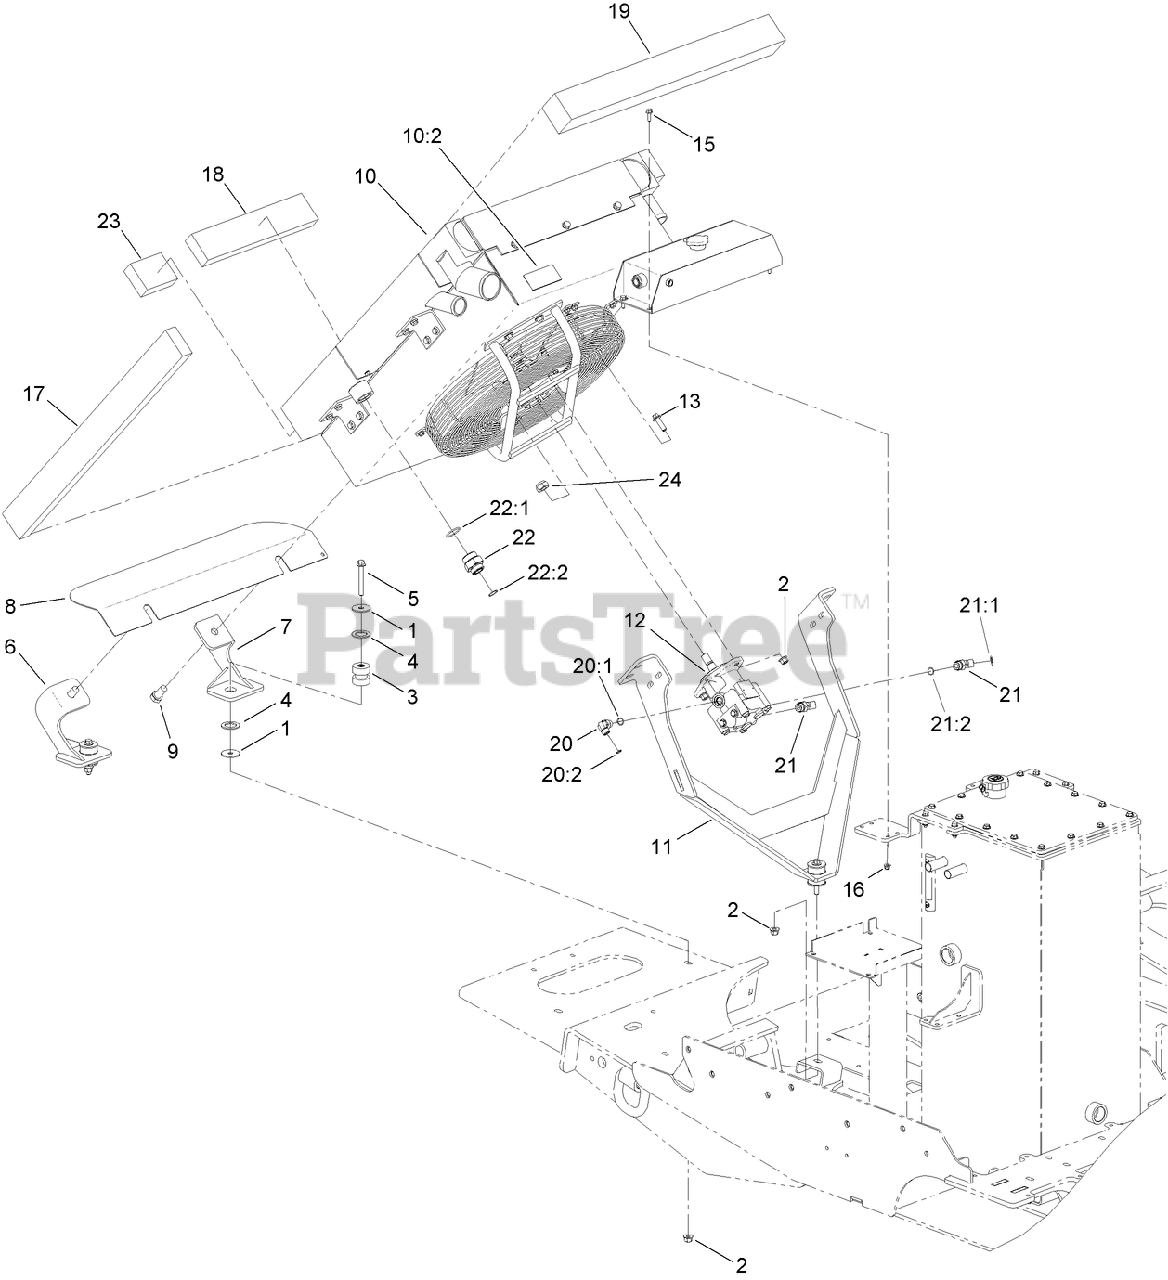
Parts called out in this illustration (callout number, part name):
1	WASHER-FLAT
2	NUT-LOCK, HHF
3	ISOLATOR-MOUNTING, UNIVERSAL
5	SCREW-HHF
6	SUPPORT-ISOLATOR, LH
7	SUPPORT-ISOLATOR, RH
8	PLATE-SEAL, REAR HOOD
10	COOLING ASM
10:2	DECAL-ROTATING FAN HAZARD
11	ISOLATOR-SUPPORT
12	HYD MOTOR ASM
13	SCREW-HHF
15	SCREW-HHF
16	NUT-LOCK, HHF
17	FOAM-POLYURETHANE
18	FOAM-POLYURETHANE
19	FOAM-POLYURETHANE
20	FITTING-ELBOW-90 DEG
20:1	O-RING
20:2	O-RING
21	FITTING-HYD, 45 DEG
21:1	O-RING
21:2	O-RING
22	FITTING-STR
22:1	O-RING
22:2	O-RING
23	FOAM-POLYURETHANE
24	NUT-LOCK, NI
